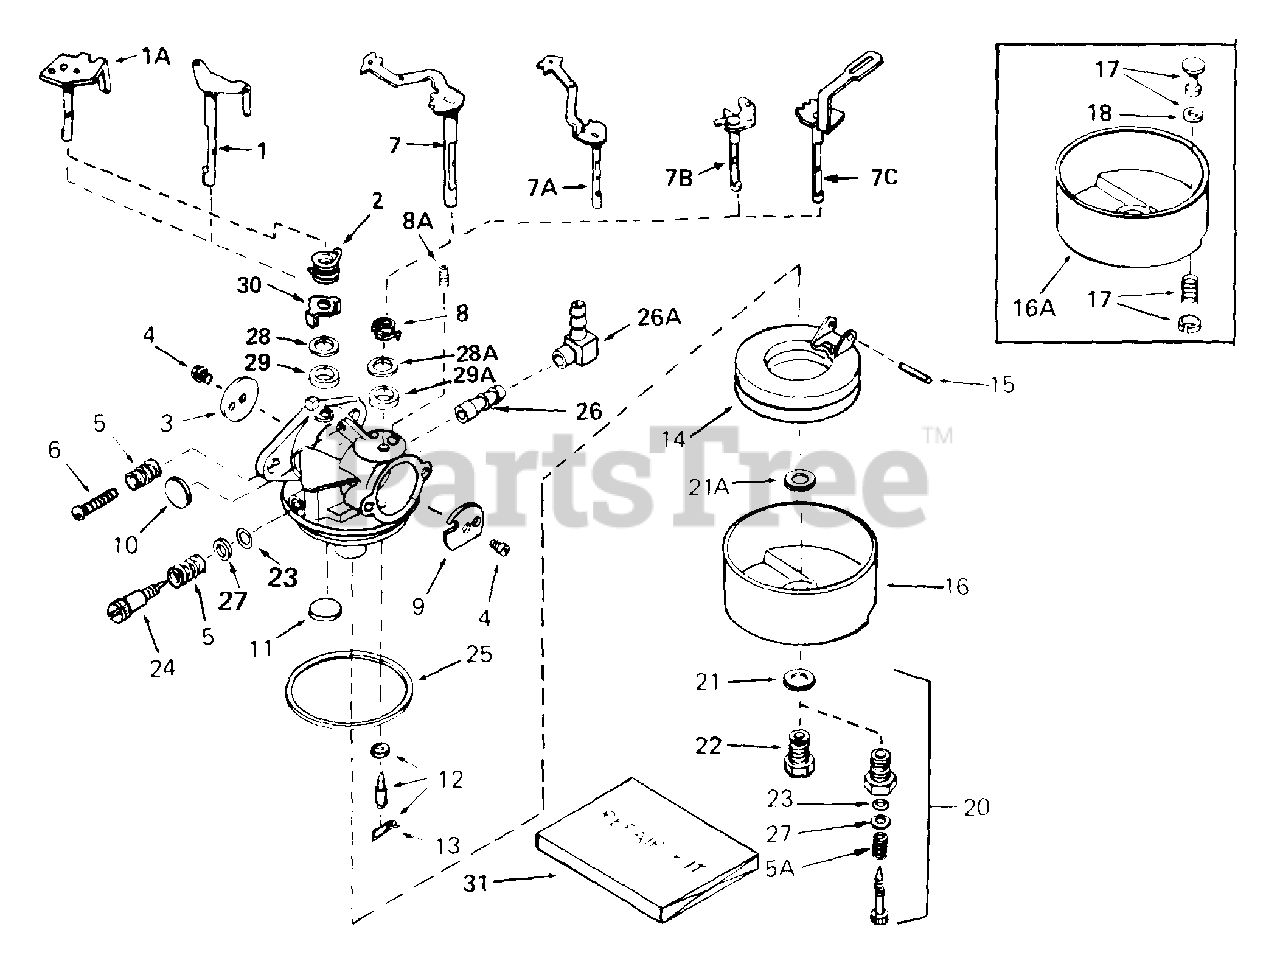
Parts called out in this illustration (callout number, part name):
1A	"Shaft & Lever Assy., Throttle
2	Spring, Throttle return
3	Shutter, Throttle
4	Screw, Throttle & Choke
12	Inlet Needle, Seat & Clip Assy.
13	Clip, Inlet needle
14	Float, Carburetor
15	Shaft, Float
16	Bowl, Float
21	Gasket, Bowl-to-body
21A	Gasket, Bowl-to-body
22	Nut, Float bowl
25	Gasket, Bowl-to-body
26A	Fitting, Fuel
